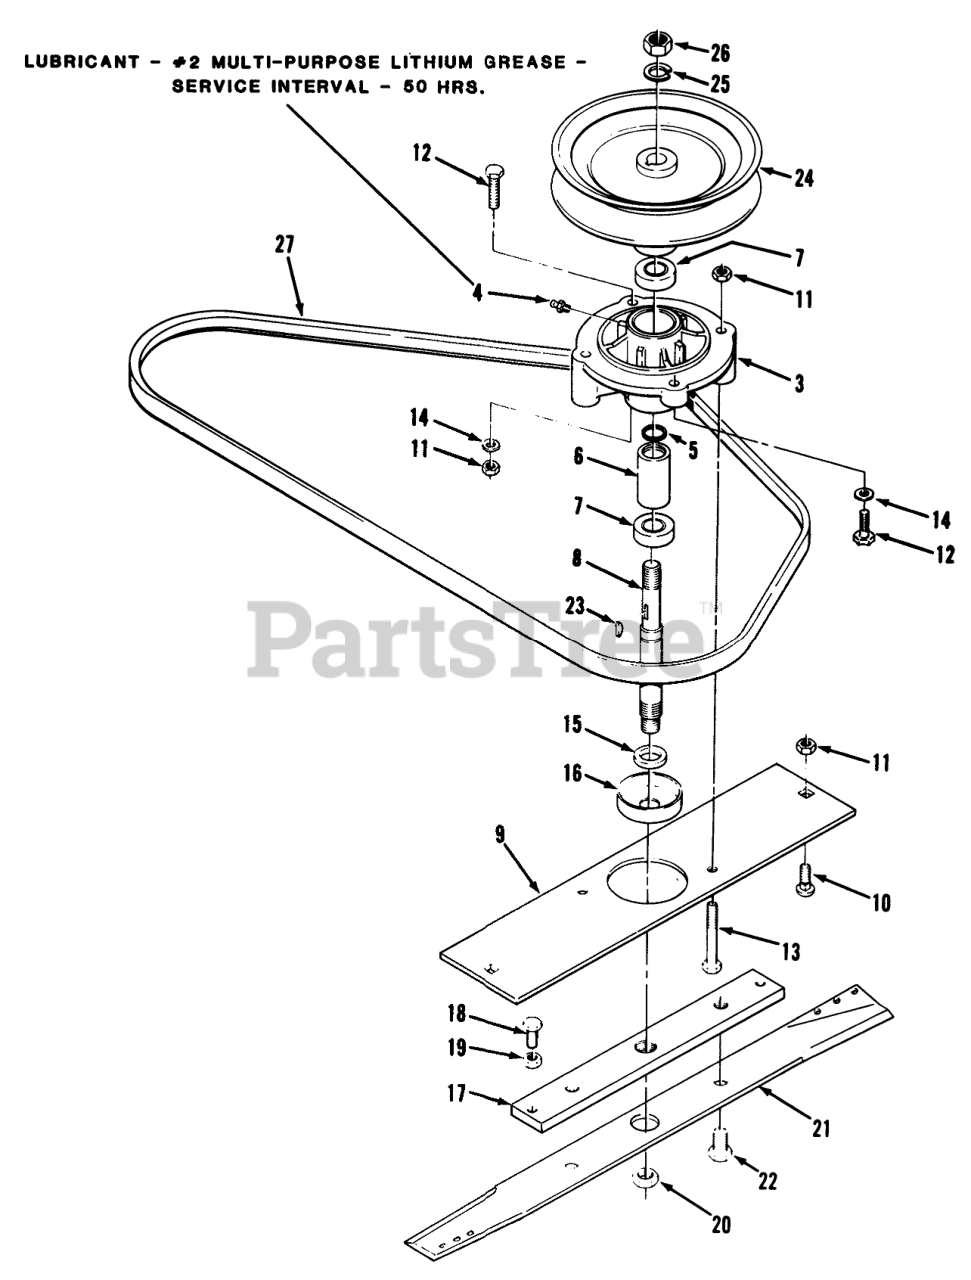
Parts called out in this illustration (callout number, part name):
3	HOUSING-SPINDLE
4	ZERK FITTING
5	SNAP RING
7	BALL BEARING
8	SHAFT
9	BAR R
10	BOLT-CARR
11	NUT-LOCK, NI
12	SCREW-HH
13	SCREW-HH
14	NUT-LOCK, NI
15	SPACER-BLADE
16	CUP-SPINDLE
17	BAR-BLADE R
18	SCREW-HH
19	NUT-HEX, JAM
20	NUT-JAM
21	Blade
22	HEX BOLT 1/2-13X3/4
23	KEY-HI-PRO
24	PULLEY HUB ASSY
25	WASHER-LOCK
26	NUT-HEX
27	V-BELT DRIVE
